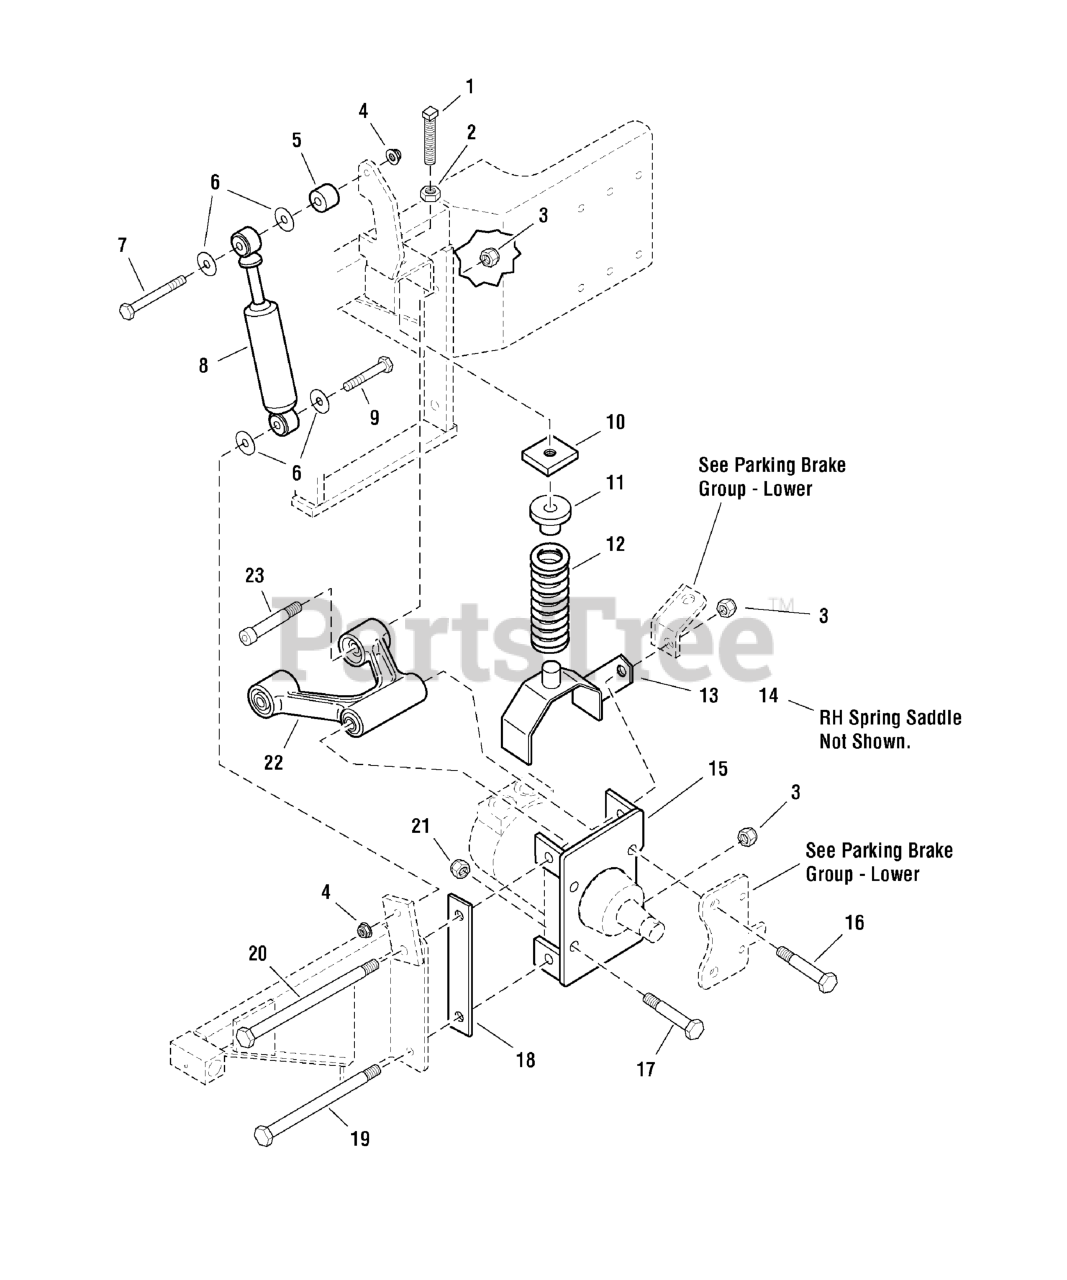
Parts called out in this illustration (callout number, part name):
1	SET SCREW, Square Head, 1/2-13 x 3
2	NUT, 1/2-13 Hex Jam
3	NUT, 1/2-13 HEX NYLON LOCK
4	NUT, 3/8-16 Hex Nylock Flange
5	SPACER, .39 x 1.00 x .75
6	WASHER, 3/8" Fender
7	BOLT, 3/8-16 X 2-3/4" GD5 CZ
8	KIT, SHOCK W/OUT COIL
9	BOLT, 3/8-16 X 2, GD5, CZ
10	SPRING COMPRESSION PLATE
11	SPRING RETAINER
12	SPRING, Compression
13	SPRING SADDLE-LH
15	WHEEL MOTOR MOUNT
16	BOLT, 1/2-20 x 3
17	BOLT, 1/2-20 X 2-1/2" GD5 CZ
18	SPACER PLATE
19	BOLT, 1/2-13 x 6-1/2
20	BOLT, 1/2-13 X 7-1/2 GD8, CZ
21	NUT, Hex, Nylon Lock, 1/2-20
22	ASSM, A-ARM WITH BEARINGS
23	BOLT, Allen Head, 1/2-13 x 3
